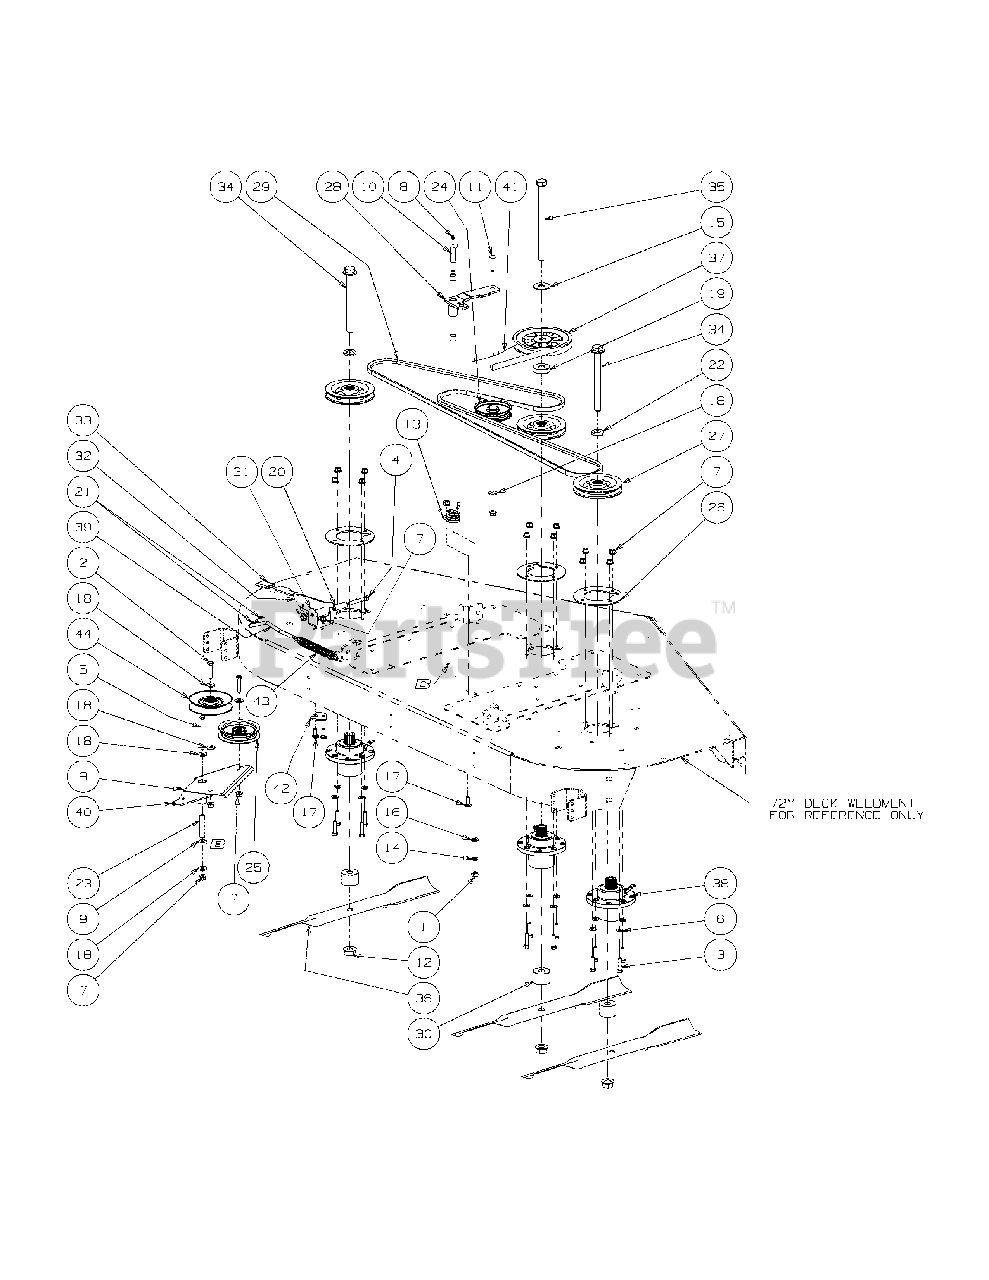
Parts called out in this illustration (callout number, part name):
1	Hex Nut, 7/16-14
2	Hex Cap Screw, 3/8-16 x 1-3/4
3	Hex Cap Screw, 3/8-16 x 1-1/2
4	Hex Cap Screw, 3/8-16 x 2-1/2
5	Hex Cap Screw, 3/8-16, 4.00
6	Flat Washer, 3/8
7	Flange Lock Hex Nut, 3/8-16
8	Grease Fitting, 1/4-28 x 3/16
9	Idler Washer
10	Shoulder Screw, 7/16-14
11	Hex Carriage Screw, 3/8-16, 1.75
12	Flange Hex Nut, 3/4-16
13	Torsion Idler Spring
14	Lock Washer, 7/16
15	Flat Washer, .781 ID 2.00 OD, .105
16	Flat Washer, .469 ID, .875 OD, .105
17	Carriage Bolt, 3/8-16 x 1
18	Flat Washer, .406 ID, 1.0 OD, .105
19	Spacer, .76 ID x 2.0 OD x .477
20	Spacer, .39 ID x .63 OD x 1.75
21	Cotter Pin, .072 x 1.12 Long
22	Spacer .812 ID x .268 LG
23	Spacer, .39 ID x .625 OD x 2.75
24	Flat Pulley
25	PULLEY-FLAT IDLER 4.875
26	Aluminum Spindle Support Plate
27	V-Pulley, 5.75 OD
28	Idler Arm Assembly, Deck
29	V-Belt, B Section x 124.0 LG
30	Spacer, .760 ID x 2.00 OD x .330
31	Tension Idler U-Bracket
32	Handle Tension Weldment
33	Tension Idler Handle Grip
34	Hex Cap Screw, 3/4-16, 7.50
35	Hex Cap Screw, 3/4-16, 9.50
36	Bahia Blade, 25.0, .756 ID
37	V-Pulley, 6.360 OD x .750 Bore, Cast
37	V-Pulley, 7.450 OD x .750 Bore, Cast
38	Aluminum Spindle Assembly
39	Spring Tension Rod
40	Idler Arm Assembly Service kit
41	V-Belt, B Section x 102 LG
41	V-Belt, B Section x 107.0
42	Adaptor Plate
43	Extension Spring, 1.0 OD x 5.00
43	Extension Spring, 1.0 x OD x 7.50
44	Idler Pulley, 5.06 Dia.
